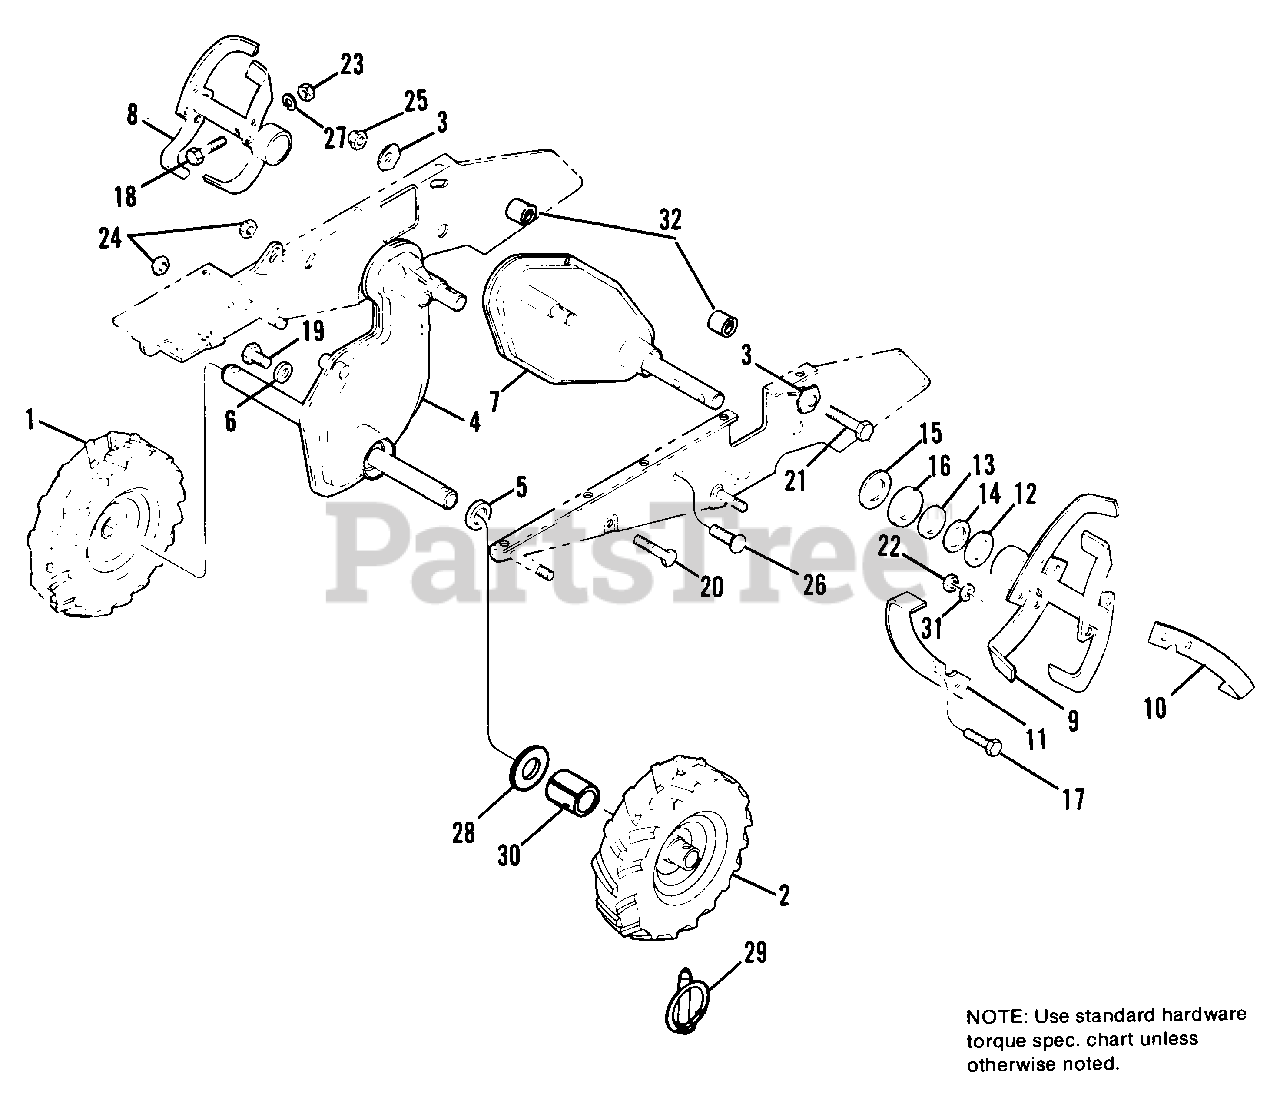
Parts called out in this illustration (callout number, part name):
1	TIRE & WHEEL ASSEMBLY-R.H.
2	TIRE & WHEEL ASSEMBLY-L.H.
3	PYRAMIDAL LOCKWASHER
4	CHAIN CASE ASSEMBLY-Wheel Drive
6	NYLON WASHER
7	CHAIN CASE ASSEMBLY-Tine Drive
8	TINE ASSEMBLY-R.H.
9	TINE ASSEMBLY-L.H.
10	TINE-R.H.
11	TINE-L.H.
12	FELT SEAL
13	FELT SEAL
15	WASHER-Back Up
16	FELT SEAL
17	TINE BOLT
18	CAP SCREW, Hex Hd. 3/8-24 x 1-3/4" Heat Treated
19	CAP SCREW, Hex Hd. 5/16-18 x 1/2" Plated
20	CAP SCREW, Hex Hd. 5/16-18 x 1-5/8" Plated
21	CAP SCREW, Hex Hd. 5/16-18 x 2-1/2" Plated & Heat Treated
22	NUT, Hex 7/16-20
23	NUT, Hex 3/8-24
24	NUT, Center Lock, 5/16-18
25	NUT, Center Lock, 5/16-18
26	BOLT, Carriage 5/16-18 x 2-1/4" Plated
27	WASHER, Spring Lock 3/8
30	SPACER-Wheel
31	WASHER, Spring Lock 7/16
32	SPACER
